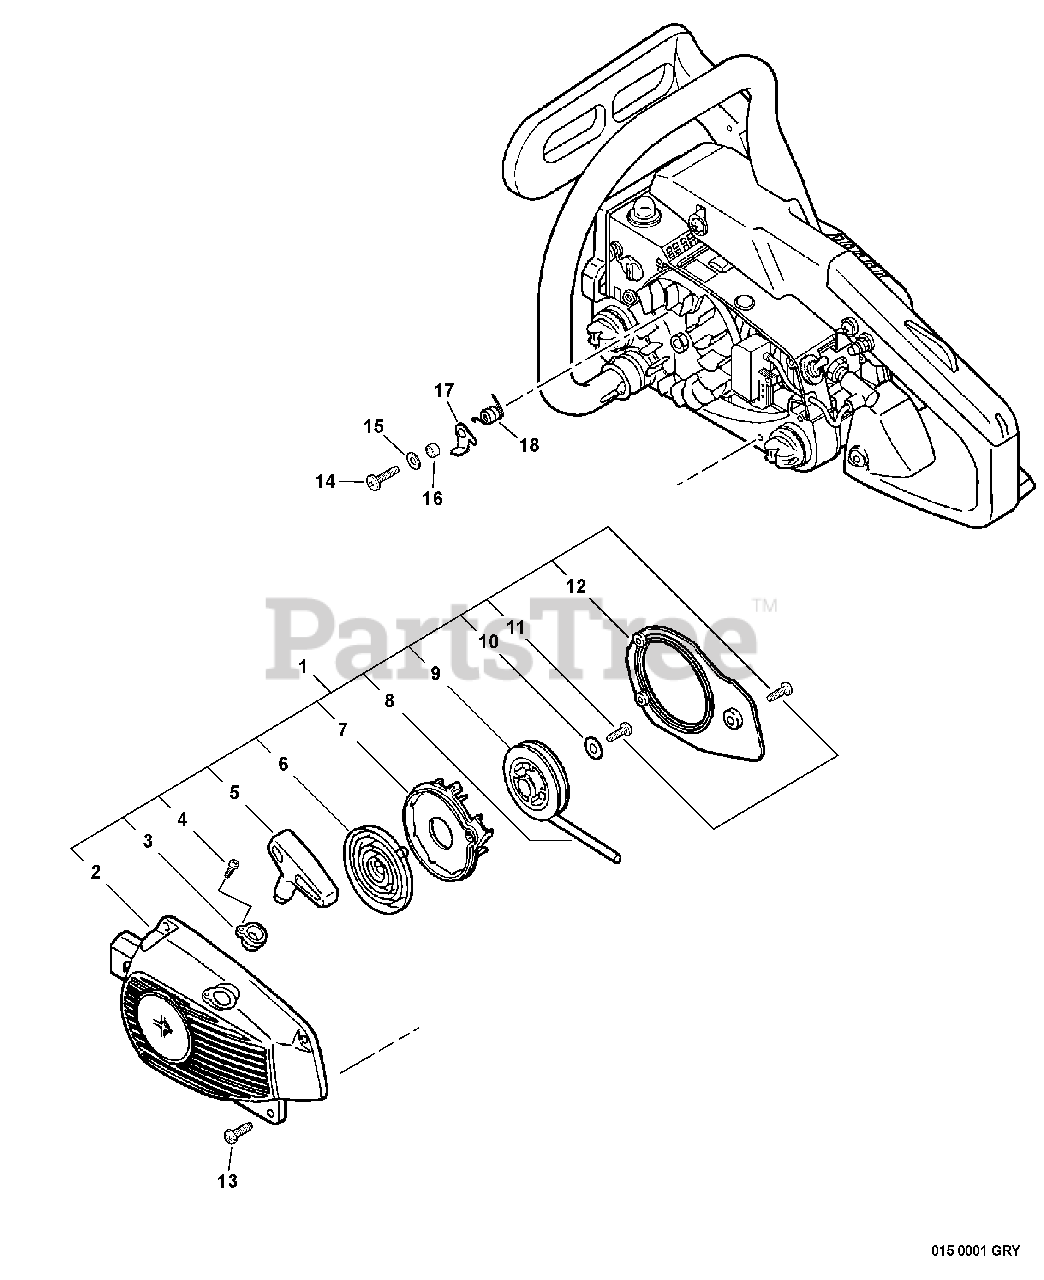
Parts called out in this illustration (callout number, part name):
1	STARTER ASSY
2	CASE, STARTER
3	GUIDE, ROPE
4	SCREW 3×14
5	GRIP, STARTER
6	SPRING, RECOIL
7	PLATE, STARTER
8	ROPE, STARTER 3.0×850
9	REEL, ROPE
10	WASHER 4.1×15.5×1T
11	SCREW 4×14
13	SCREW 4×16
14	SCREW 5×12
15	WASHER 5.5×12×0.8
16	SPACER 5.2×8×2.1
17	PAWL, STARTER
18	SPRING, TORSION
